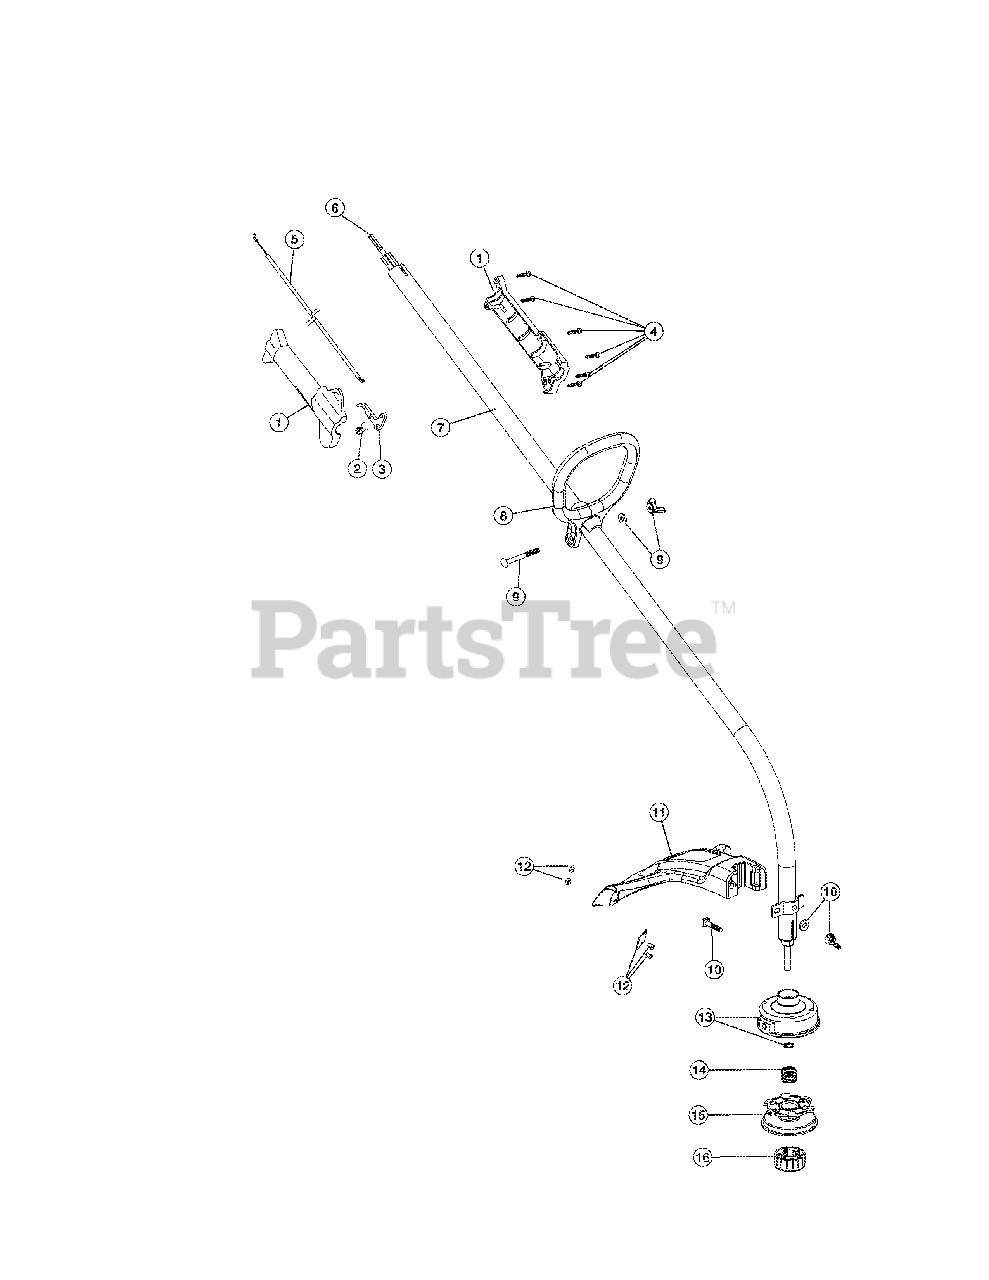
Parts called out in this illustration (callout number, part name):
1	Throttle Housing Assembly (includes 2 - 4)
2	Throttle Trigger Spring
3	Throttle Trigger
4	Throttle Housing Screws
5	Throttle Cable
6	Flexible Drive Shaft
7	Drive Shaft Housing
8	D-Handle Assembly (includes 9)
9	D-Handle Hardware
10	Guard Mounting Hardware
12	Blade Assembly
13	Outer Reel w/Retainer
15	Inner Reel
16	Bump Knob
